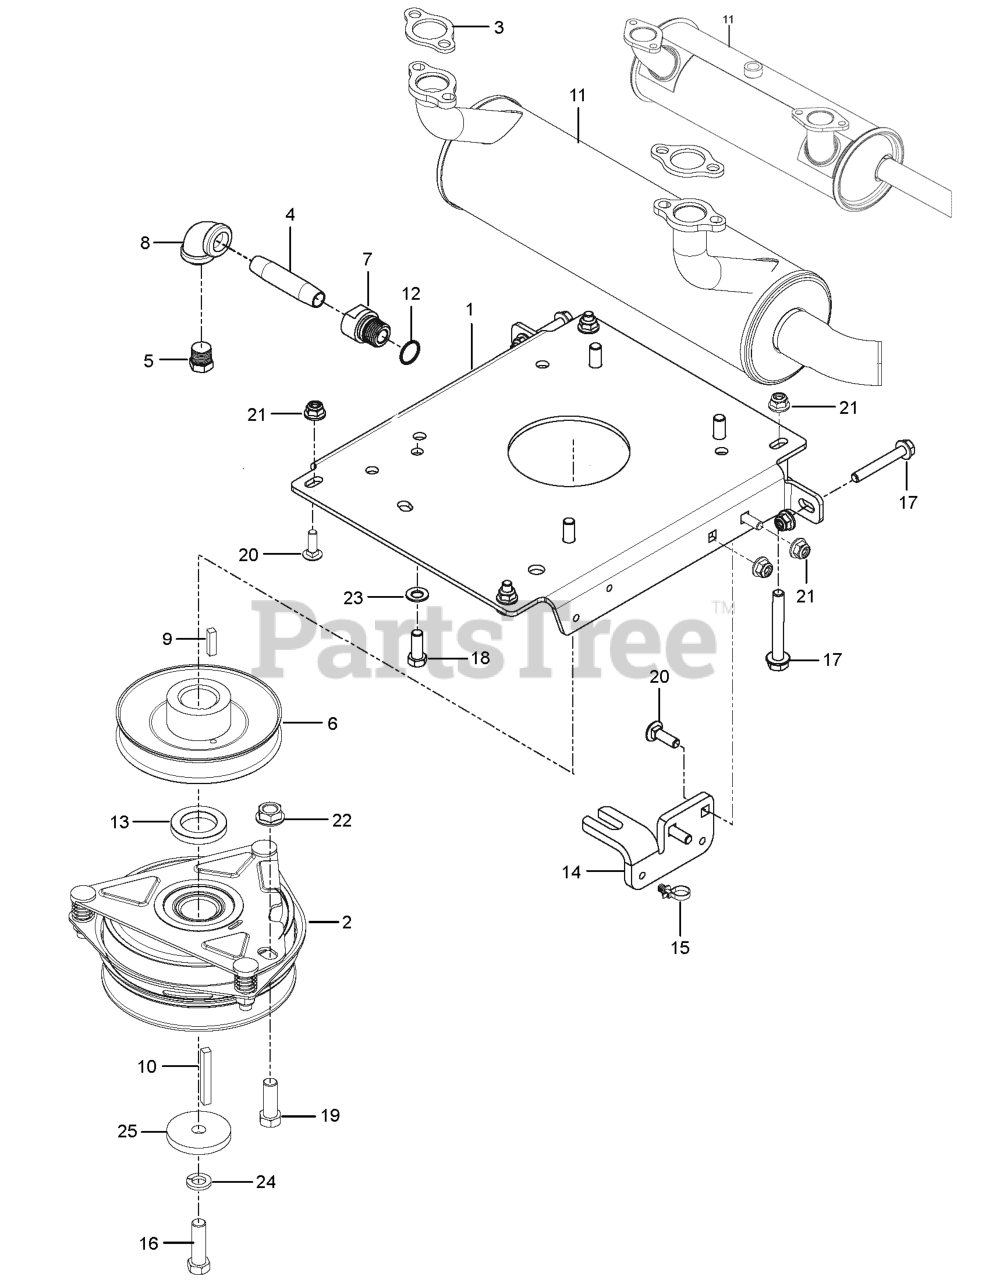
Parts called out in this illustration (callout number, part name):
1	PLATE.PNT.ENGINE.PZ/PZT.EDIP
2	CLUTCH, 150 FT/LBS
3	GASKET.EXHAUST.KAWASAKI
4	PIPE NIPPLE 3/8 X 3
5	PLUG, DRAIN 3/8 NPTF
6	PULLEY, ENGINE
7	ADAPTER, OIL DRAIN
8	90 DEG.ELBOW 3/8NPT
9	KEY 1/4 SQ X 1.0
10	KEY 1/4 SQ X 2
11	MUFFLER, 29HP KAW FX751V-850V
11	MUFFLER.KOH.EFI.W/O2.SENSOR
13	SPACER, .25 X 1.135 I.D.
14	STOP, CLUTCH, OGURA
15	TIE WRAP, 8-3/8", W/CLIP
16	CLUTCH BOLT7/16-20X1.5GR5.96HR
17	HHFS 5/16-18 X 2.25 GD 5
18	HCS 3/8-16X1.GRD.5.ZD
18	HHFS 5/16-18 X 1.5 GD 5
19	HCS 7/16-14 X 1-1/4 GR 5 ZD
20	RHSNB 5/16C X 1
21	5/16-18 NYLOC FLANGE NUT
22	NUT 7/16C WHIZ
23	WASHER, 3/8 DISC SPRING SPEC
24	WASHER 7/16 LOCK
25	BLADE WASHER
